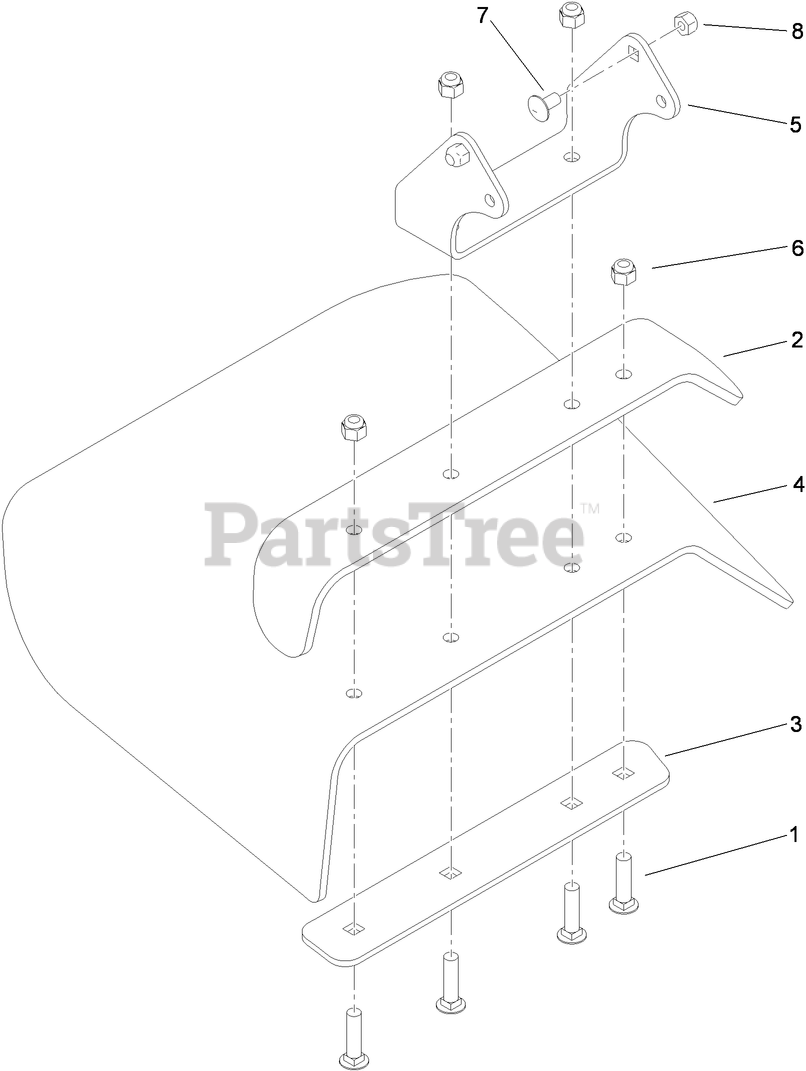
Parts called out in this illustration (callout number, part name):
1	SCREW-CARR
2	DEFLECTOR
3	STRAP-DISCHARGE
4	DEFLECTOR-RUBBER
5	BRACKET-MOUNTING, DEFLECTOR
6	NUT-LOCK, NI
7	SCREW-CARR
8	NUT-LOCK, NI
